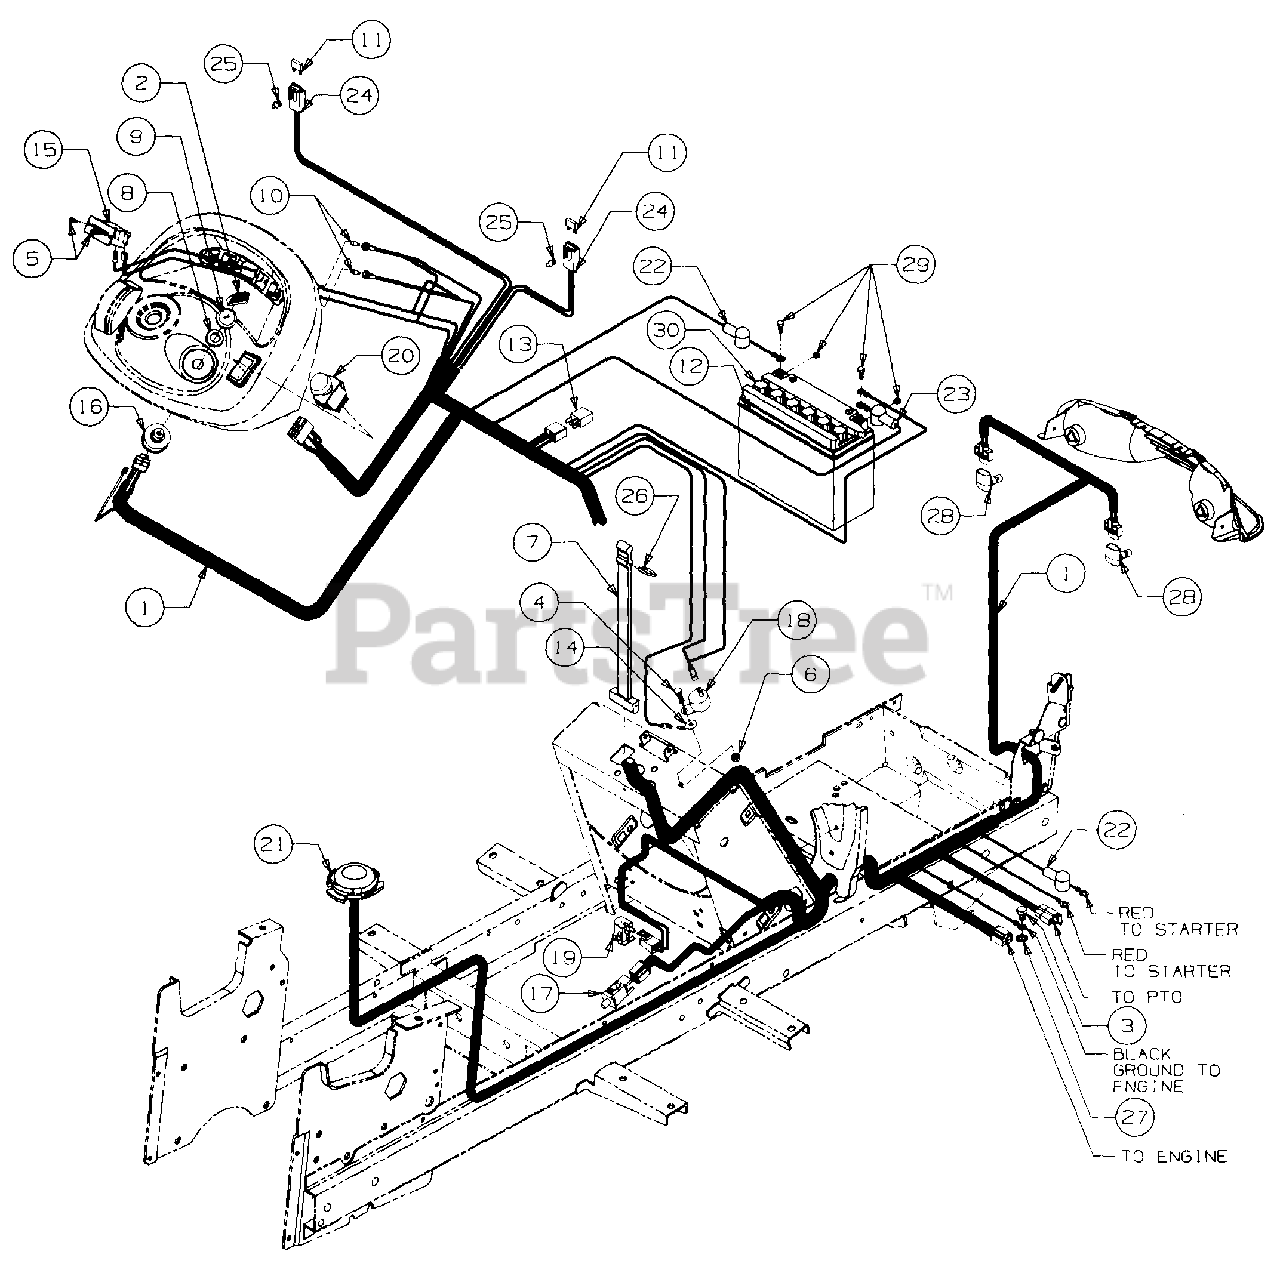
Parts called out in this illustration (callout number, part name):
1	Main Harness
2	Key, Ignition (Set of 2)
3	Screw, Hex Cap, 3/8-16 x .50 Lg
4	Screw, Hex Cap, 1/4-20 x 1.0 Lg
5	Screw, Truss Hd Tapp, #6 x .62 Lg
6	Nut, Hex Sems, 1/4-20
7	Strap, Battery Retainer
8	Nut, Ignition Switch
9	Cap, Ignition Switch
10	Bulb, Indicator
11	Fuse, 20 Amp
13	Relay
14	Lug, Quick Connect
15	Hour Motor
16	Switch, Ignition
17	Switch, Interlock (Brake)
18	Indicator, Voltage
19	Switch, Snap Mount - Closed (Reverse) Normally
20	Switch, PTO
21	Switch, Seat
22	Cover, Terminal Red
23	Cover, Terminal Black
24	Holder, Fuse
25	Clip, Fuse Holder Mtg.
26	Hook, Wire Rectangular
27	Washer, External Lock, 318
28	Bulb, Head Lamp
29	Bolt, Battery (Set of 2)
30	Cap, Battery
